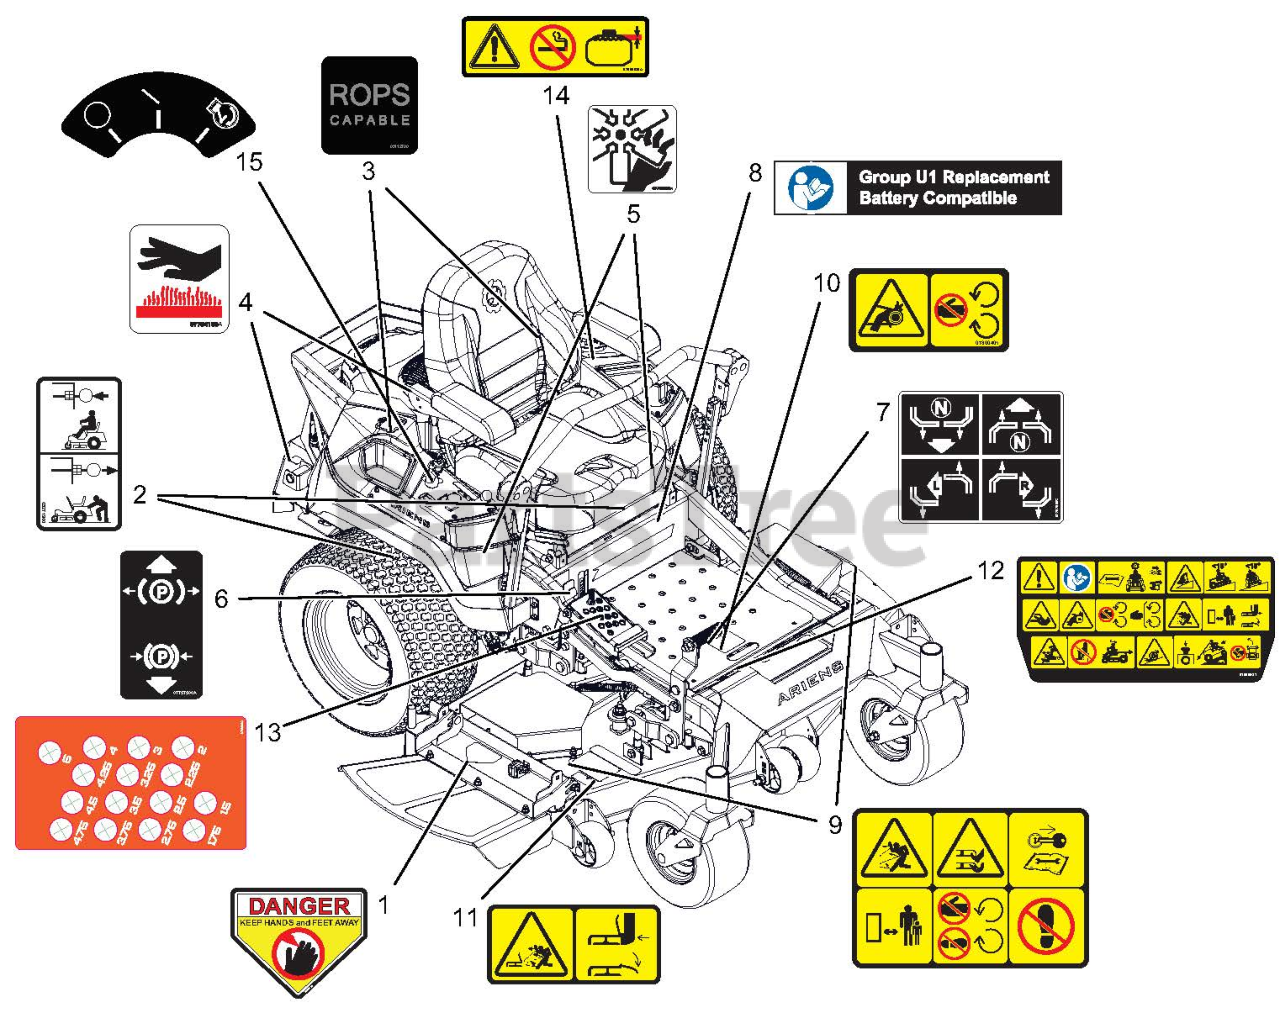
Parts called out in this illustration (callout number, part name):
1	DECAL, DANGER
2	DECAL, TRANSMISSION DISCONNECT
3	DECAL, ROPS LOCATION
4	DECAL, HOT SURFACE
5	DECAL, DANGER FAN
6	DECAL, PARKING BRAKE LEVER
7	DECAL, INSTRUCTIONAL-STEERING
8	DECAL, U1 BATTERY REPLACEMENT
9	DECAL, SAFETY - MOWER DECK
10	DECAL, SAFETY - GUARDING
11	DECAL, SAFETY - DECK GUARDING
12	DECAL, MAIN SAFETY
13	DECAL, ARIENS HOC
14	DECAL, FUEL WARNING
15	DECAL, KEYSWITCH
